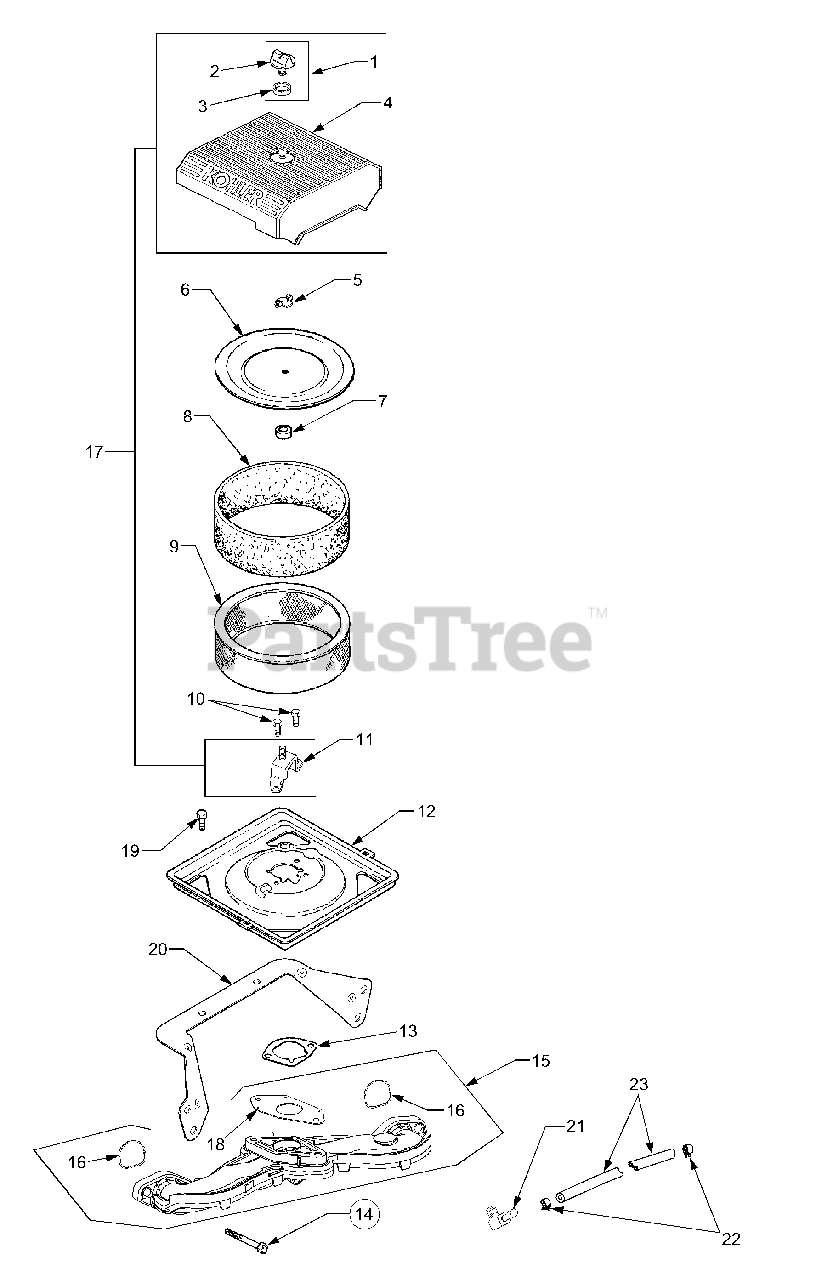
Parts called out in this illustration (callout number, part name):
1	Kit, Knob w/Seal
3	Seal, Air Cleaner Cover Knob
4	Cover, Air Cleaner
6	Cover, Inner Air Cleaner
7	Seal, Inner Air Cleaner
8	Precleaner, Element
9	Element, Air Cleaner
10	Screw, Hex Flange, M6 x 1.0 x 16
11	Bracket, Air Cleaner Base
12	Base, Air Cleaner
13	Gasket, Air Cleaner Base
14	Screw, Hex Flange, M6 x 1.0 x 40
15	Manifold, Intake
16	O-Ring, Intake Manifold
17	Kit, Air Cleaner Cover
18	Gasket, Carburetor
19	Screw, Hex Flng, M5 x 0.8 x 10
20	Bracket, Air Cleaner Base
21	Connector, Hose 90°.
22	Clamp, Hose
23	Line, Fuel 17"
